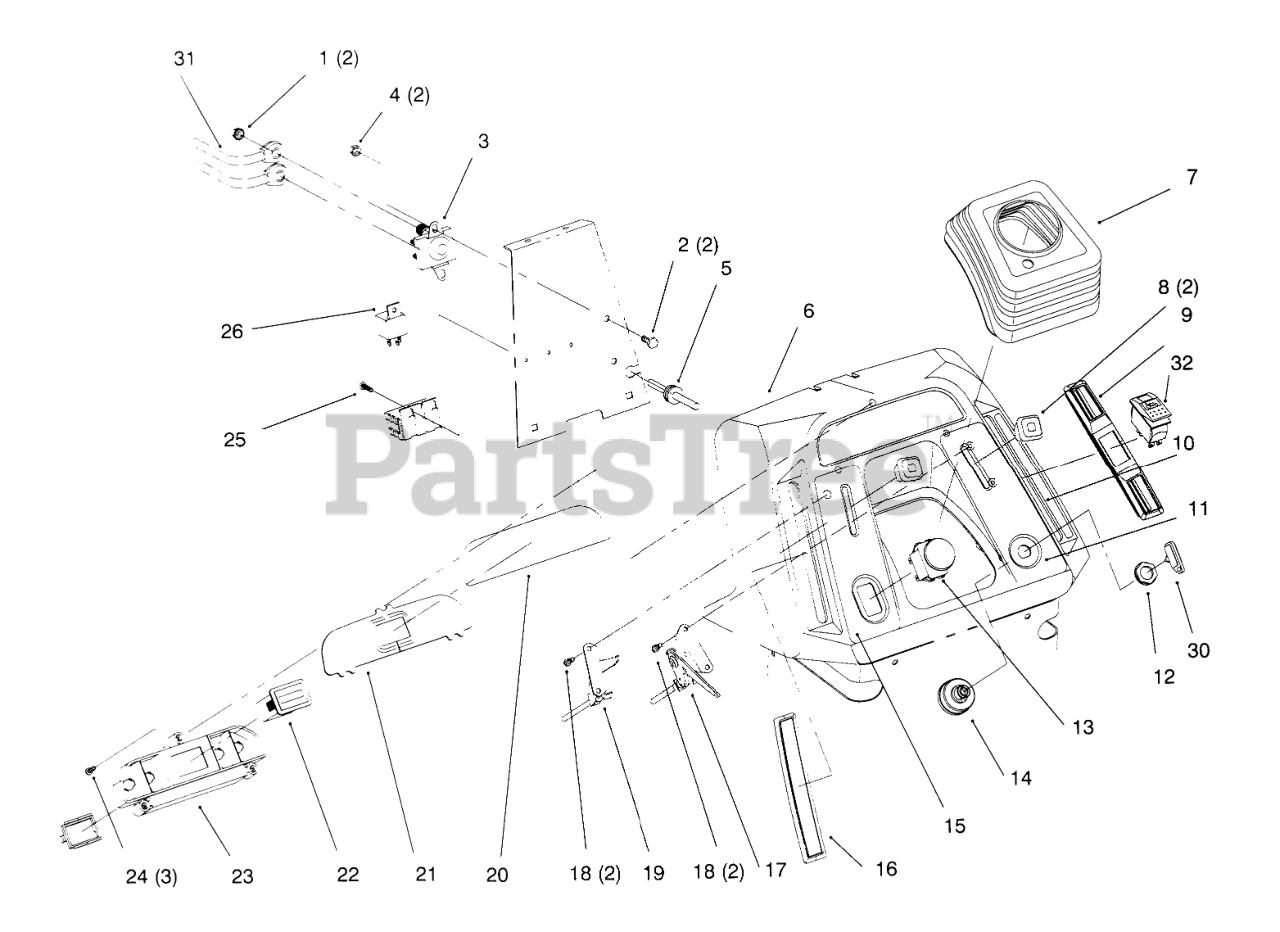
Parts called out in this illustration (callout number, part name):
1	Nut-Hex Lock (Only On: 72042,72043,72062,72063)
2	Screw-HH (Only On: 72042,72043,72062,72063)
3	Solenoid (Only On: 72042,72043,72062,72063)
4	Nut-Lock (Only On: 72042,72043,72062,72063)
5	GROMMET-RUBBER
6	Dash (Only On: 72042,72062)
6	Dash (Only On: 72043,72063,72103)
7	BOOT-STEERING
9	Cover-Slot RH (Only On: 72043,72063)
9	Cover-Cruise (Only On: 72103)
10	Decal-Shift (Only On: 72042,72062)
11	Decal-Throttle/Ignition (Only On: 72042,72043)
11	Decal-Throttle/Ignition (Only On: 72062,72063,72103)
13	Switch-PTO
14	SWITCH-IGNITION
15	Decal-Choke/PTO (Only On: 72042,72043)
15	Decal-PTO/Choke (Only On: 72062,72063,72103)
16	COVER-SLOT, LH
17	Control-Throttle (Only On: 72042,72043,72062,72063)
17	Control-Throttle (Only On: 72103)
19	Control-Choke (Only On: 72042,72043,72062,72063)
19	Control-Choke (Only On: 72103)
20	Decal-Dash Lens (Only On: 72043,72103)
20	Decal-Dash Lens (Only On: 72042,72062,72063)
21	LENS-DASH
22	Hourmeter
23	Light-Indicator (Only On: 72043,72103)
23	Housing-Indicator Light (Only On: 72042,72062,72063)
24	SCREW-PPH
25	Screw-PPH (Only On: 72103)
26	Relay (Only On: 72103)
30	KEY-IGNITION
31	Cable-Battery Red (Only On: 72042,72043,72062,72063)
32	Switch-Cruise (Only On: 72103)
